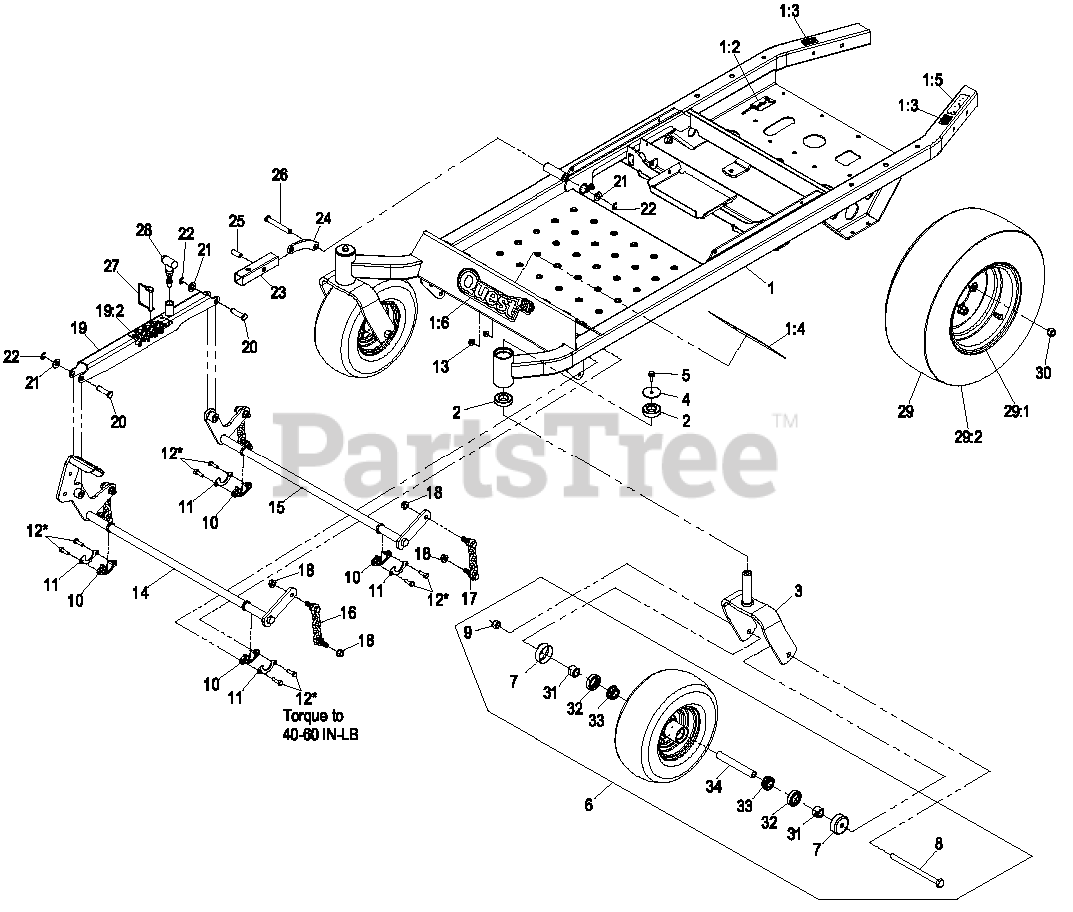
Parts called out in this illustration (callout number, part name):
1	ASM-FRAME W/ DECALS
1:2	DECAL,DRIVE RELEASE
1:3	DECAL-CAUTION
1:4	DECAL-CONSOLE
1:5	DECAL-ARRESTER, SPARK
1:6	DECAL-QUEST SP LOGO
2	BEARING-BALL
3	WLD,CASTER FORK
5	SCREW-HHF
6	ASM, WHEEL AND TIRE W/ AX
7	GUARD-SEAL
8	SCREW-HH
9	NUT-LOCK, NI
10	BUSHING-FLANGE
11	GUSSET-LIFT, DECK
12	SCREW-HH
13	NUT-HF, NI
14	WLD,DECK LIFT SHAFT FRT
15	WLD,DECK LIFT SHAFT REAR
16	DECK CHAIN ASM
17	DECK CHAIN ASM
19	ASM,HEIGHT ADJUST W/ DECA
19:2	DECAL,HEIGHT OF CUT
20	PIN-CLEVIS
21	WASHER-FLAT
22	RING-RETAINING, EXTERNAL
23	STOP-HEIGHT ADJUST
24	ARM-FLOAT LINK
25	PIN-PIVOT
26	PIN-CLEVIS
27	PIN-HITCH
28	PIN-SPRING
29	WHEEL AND TIRE ASM-20X7-1
29:1	WHEEL,10 X 6.00
29:2	TIRE,20 X 7-10
30	NUT-LUG
31	SPACER-NUT
32	SEAL-CASTER
33	BEARING-CONE, TAPERED ROLLER
